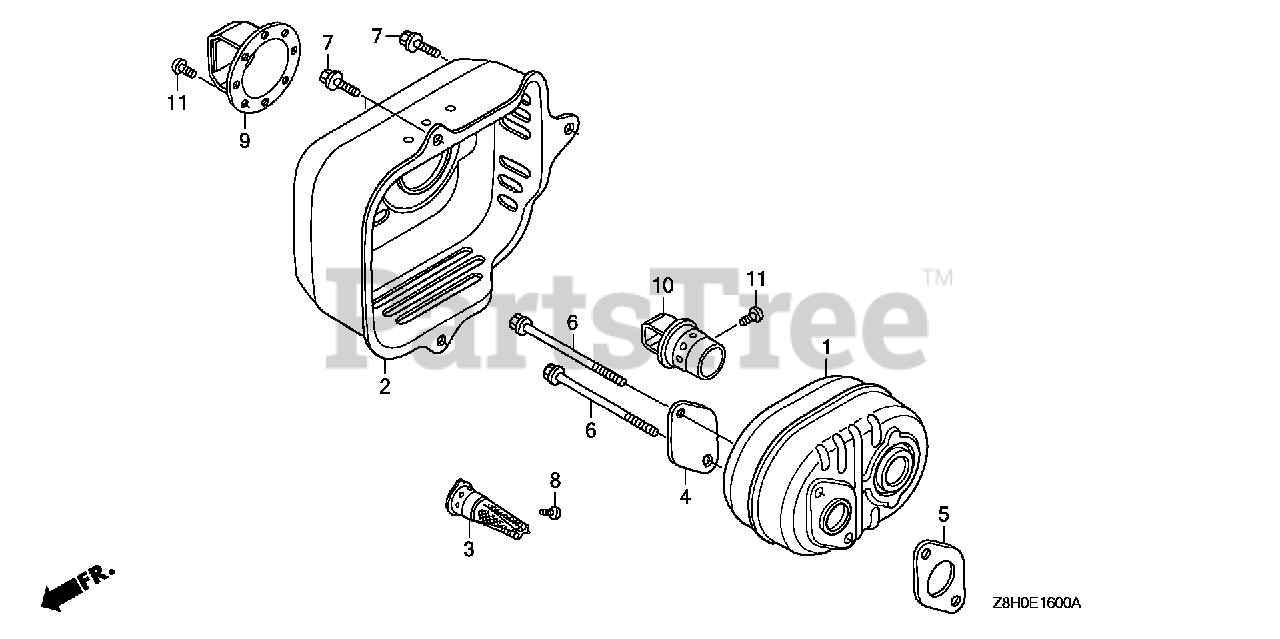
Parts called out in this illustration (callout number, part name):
2	PROTECTOR, MUFFLER
5	GASKET, MUFFLER
6	BOLT, FLANGE (6X79) (CT200)
7	BOLT, FLANGE (6X12) (CT200)
